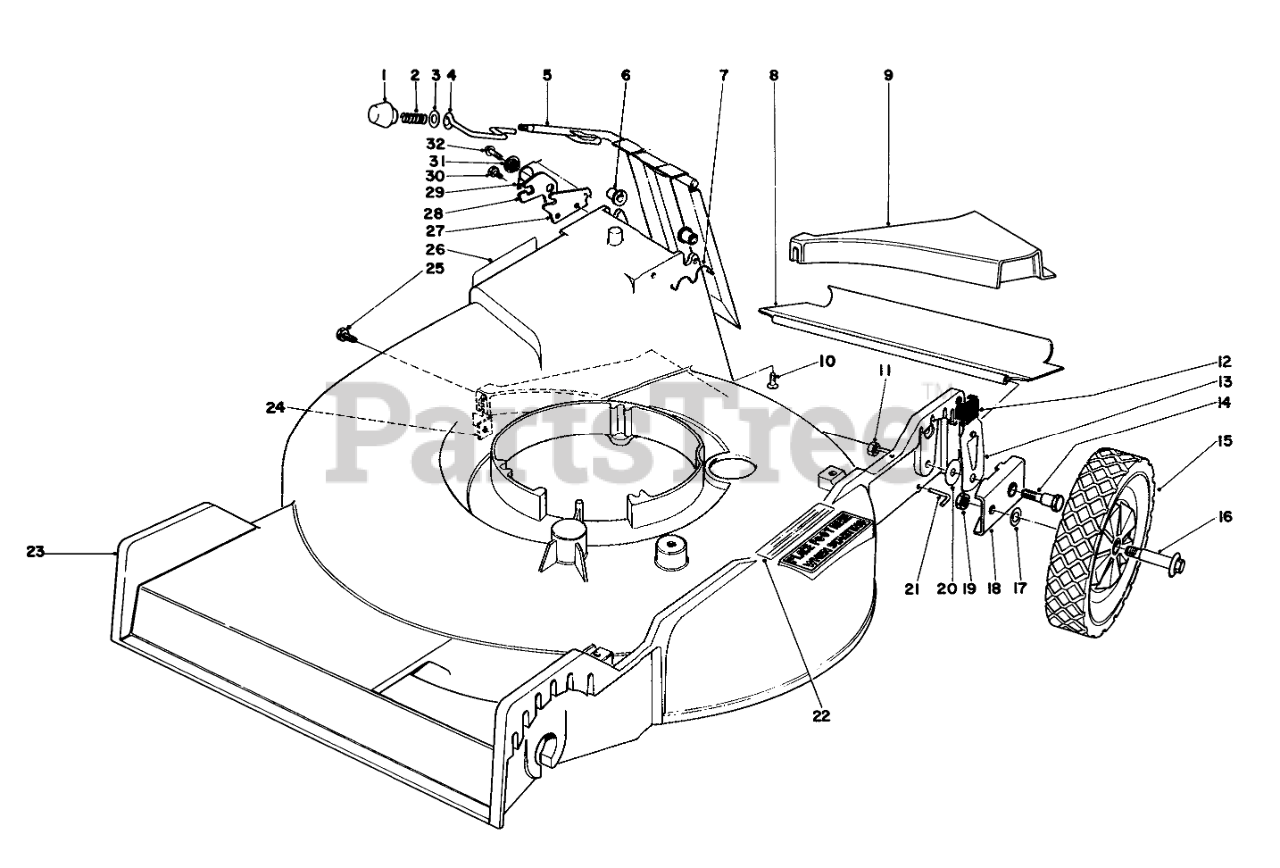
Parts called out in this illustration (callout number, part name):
2	COMPRESSION SPRING
3	WASHER
4	DOOR LATCH
5	DOOR HANDLE WA
6	BUSHING-NYLON
7	DOOR RETAINER
8	REAR SAFETY SHIELD
9	REAR INSERT
10	SCREW-HH
11	Nut
12	KNOB-ARM
13	SPRING ARM ASM HP
14	PIVOT SCREW
15	WHEEL TIRE ASM 8 IN
16	BOLT-WHEEL
17	WASHER
18	Pivot Arm
19	Nut
20	PIVOT WASHER
21	ROD-SHIELD
22	Decal Place Foot Here
23	Housing
24	SPECIAL NUT
25	SCREW THD 1/4 20 5/8
26	Decal-Attention
27	DOOR LATCH PLATE
28	SAFETY LATCH
29	TORSION SPRING
30	SCREW-HWH
31	DOOR SPACER
32	Screw
